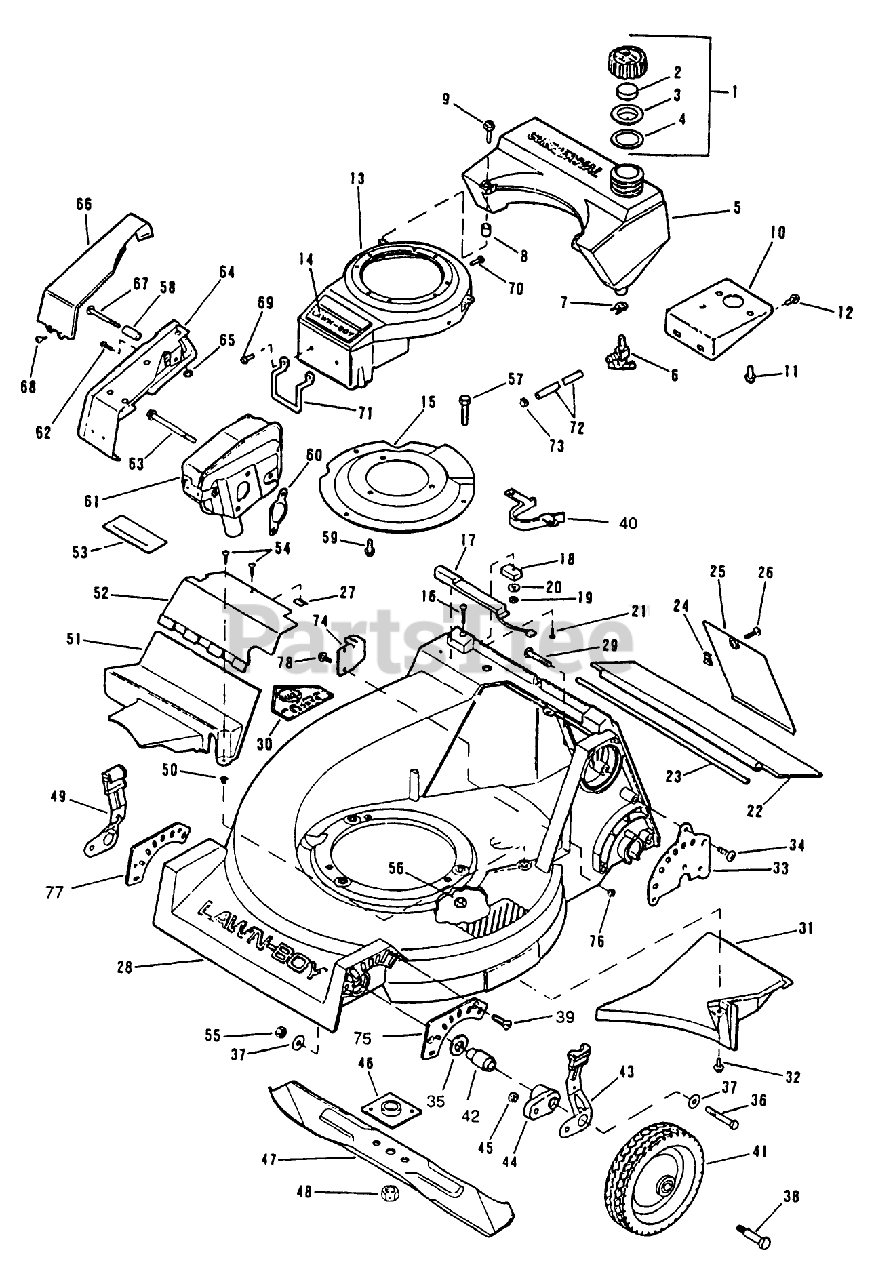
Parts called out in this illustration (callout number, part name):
1	CAP AY - F/OIL SM
2	BAFFLE - FOAM SM
3	COVER-FUEL CAP F
4	GASKET-FUELCAP SM
6	VALVE&SCREEN SM
7	CLAMP - HOSE S
8	SPACER SM
9	SCREW - SEMS SM
14	APPLIQUE SM
15	PLATE SM
24	SPEED NUT LARSON
25	DOOR-ACCESS ELECT.
26	SCREW-CROSS RECESS
27	NUT-SPEED
28	HSGN AY SERVICE
31	CHUTE BAFFLE NYL
33	PLATE HGT CMS
34	SCREW-BHTF
37	WASHER-PLAIN
41	WHEEL/TIRE ASM
43	KNOB & SPRING CMS
44	ARM HGT ADJ *BLACK
45	NUT-JAM, LOCKING
46	PLATE AND COLLAR ASM
48	NUT-BLADE
49	KNOB & SPRING CMS
50	NUT-CLIP
54	SCREW S
55	LOCKNUT
56	NUT-LOCK F
57	SCREW-HH
58	SPACER S
60	GASKET - EXH SM
62	SCREW S
63	SCREW-SEMS
64	GUARD AY-MUFFLER
65	NUT-PUSH
67	SCREW SM
68	SCREW SM
73	HOSE CLAMP SM
74	ANCHOR-CABLE
76	LOCKNUT E
